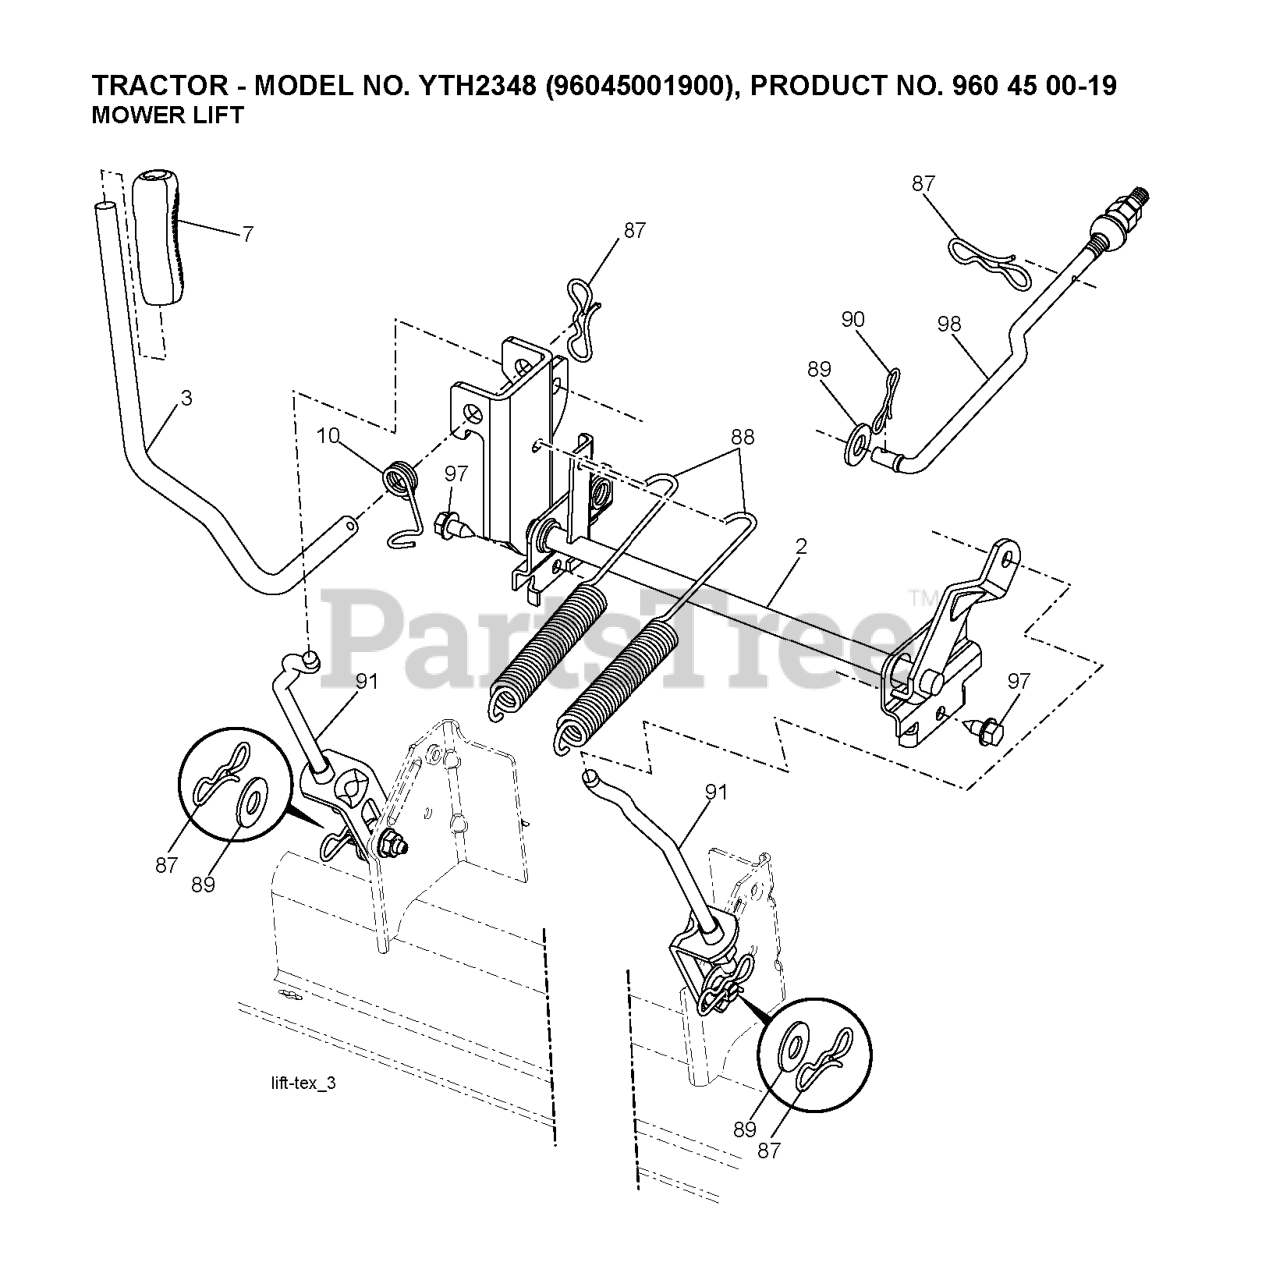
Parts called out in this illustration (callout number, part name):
2	SHAFT.ASM.LIFT.CROSS.H
3	LEVER.LIFT.HANDLE.LT
7	GRIP.HANDLE.LIFT.PVC.BLACK
10	SPRING.TORSION.LIFT.HANDLE
87	PIN.COTTER.7/16.BOW TI.
88	SPRING.LIFT.ASSIST
89	WASHER.CLEAR.ZINC
90	PIN.COTTER.5/16.BOW TI
91	LINK.ASM.LIFT.REAR
97	SCREW, 3/8-16X3/4
98	LINK.ASM.SUSP.FRONT.MWR.10.5
